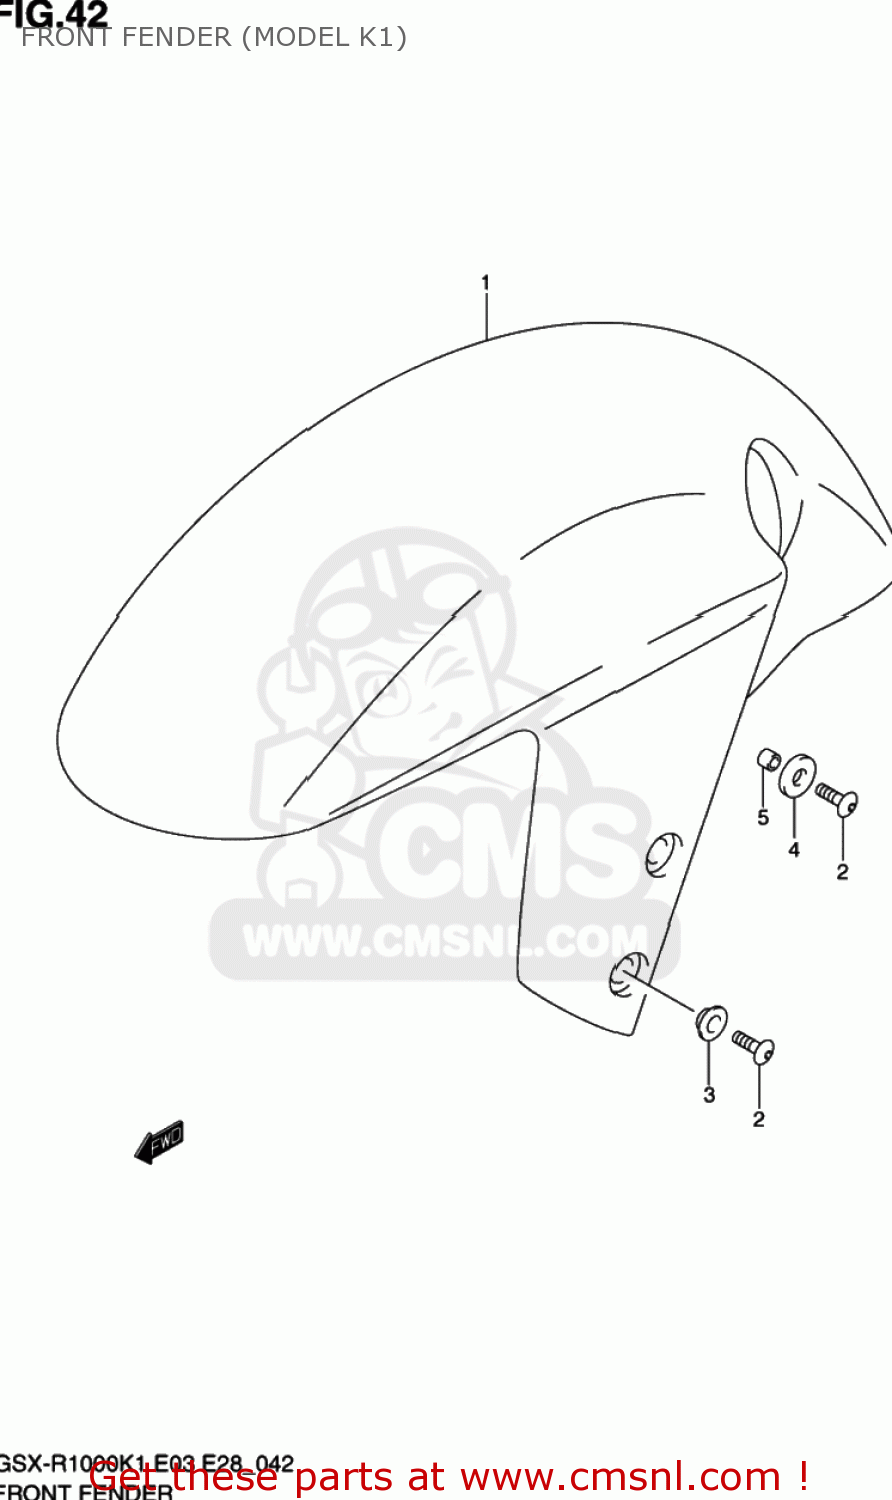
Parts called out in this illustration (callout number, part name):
1	FENDER,FR
2	SCREW(6X16)
3	WASHER(6.3X16X1.5)
4	WASHER,FR FENDER FR NO.2
5	SPACER(6.5X9X6.7)
